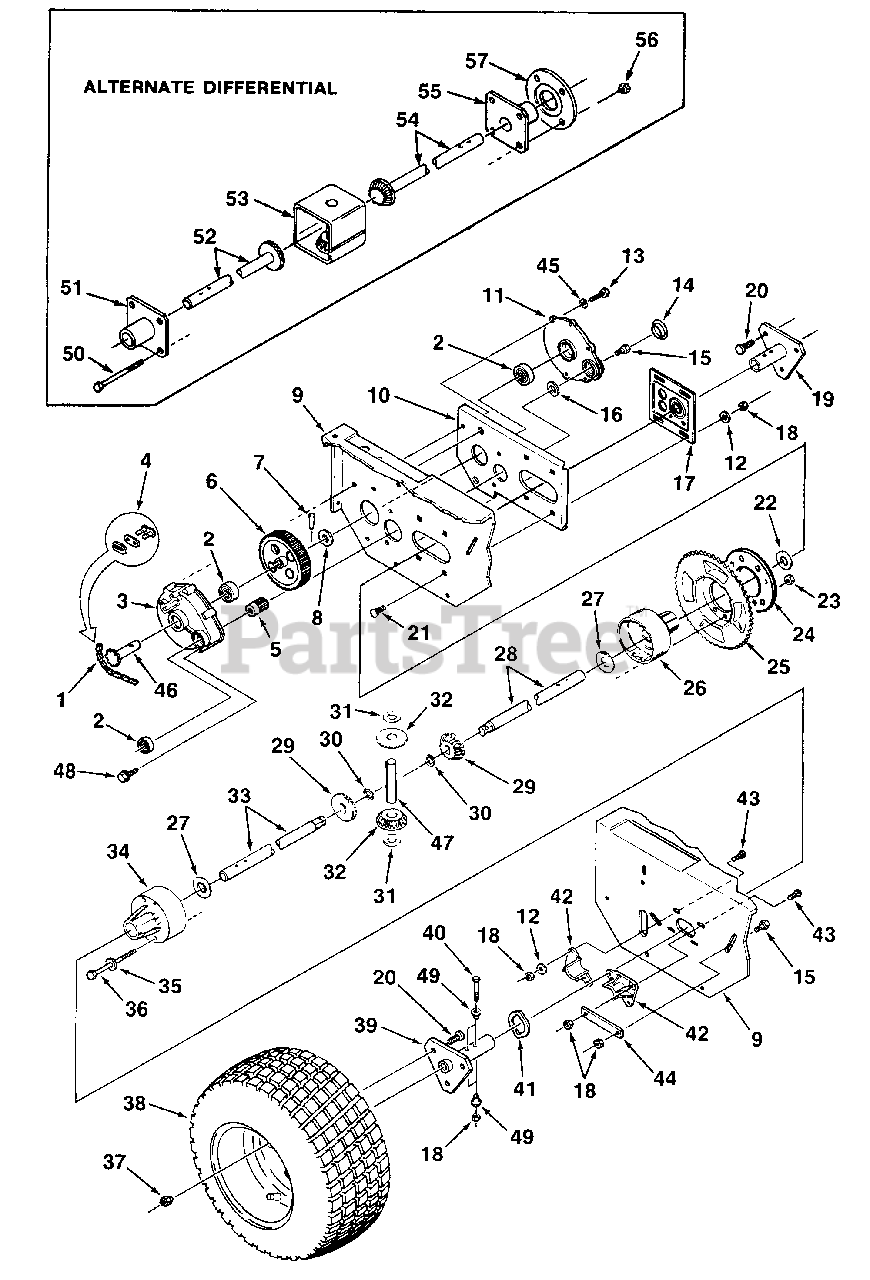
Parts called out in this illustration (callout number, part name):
1	CHAIN- Drive
3	HOUSING- Gear
4	LINK- Connecting
5	PINION- Drive
7	PIN- Gear
9	FRAME-RMX
10	SUPPORT- Frame
11	HOUSING- Gear cover
12	WASHER
14	SEAL- Gear cover
17	RETAINER & BEARING
19	TUBE- LH AXLE
22	WASHER- Flat
24	PLATE- Sprocket
25	SPROCKET- 48 tooth
26	HOUSING- Gear L.H.
28	AXLE- Short
29	GEAR- Bevel
30	RING- Snap
31	WASHER- Thrust
32	GEAR- Pinion
33	AXLE-Long
34	HOUSING- Gear R.H.
36	SCREW- Machine hex hd.
38	WHEEL & TIRE
39	TUBE & FLANGE- R.H.
41	RING- Bearing retaining
44	STRAP- Brg.
45	WASHER- Lock
47	PINION- Drive
49	WASHER- Extruded
50	SCREW- Hex (5/16 - 18 x 4)
51	CAP & BEARING (R.H.)
52	AXLE. w/gear (R.H.)
53	HOUSING & GEAR
54	AXLE w/gear (L.H.)
55	CAP & BEARING (L.H,)
56	NUT- Hex mach (5/16-18)
57	SPACER- Differential
